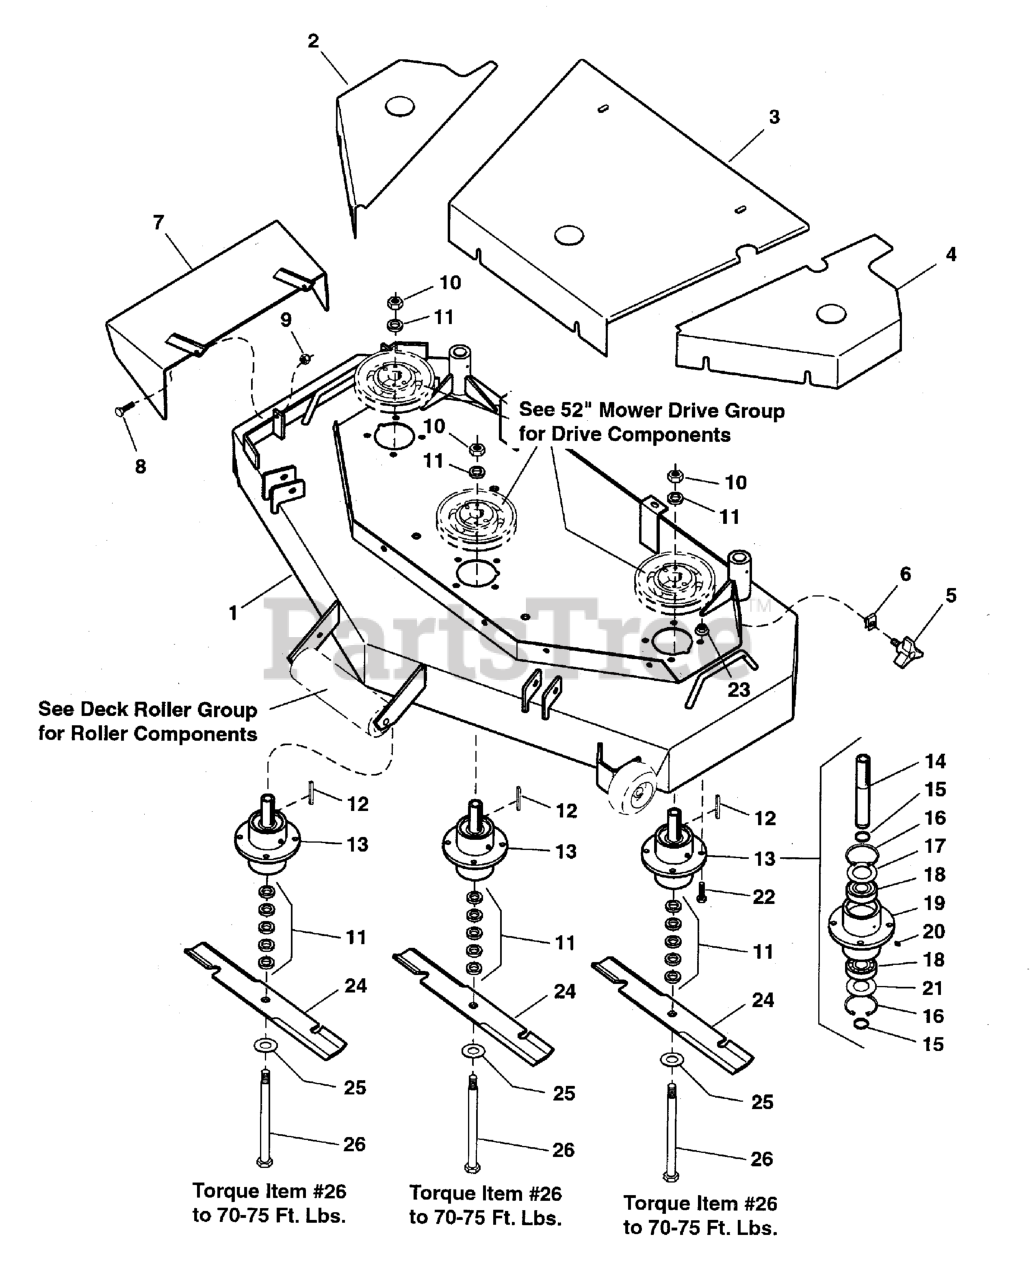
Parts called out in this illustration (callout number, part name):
1	DECK SHELL W/DECALS, 52 DDSH52
2	SPINDLE COVER, RH
3	SPINDLE COVER, Center
4	SPINDLE COVER, LH
5	KNOB
6	BODY CLIP, 5/16-18-7GA MATERIAL
7	CHUTE, DISCHARGE WELDMENT
8	BOLT, 5/16-18 X 1 GD5 YZ
9	NUT, 5/16-18 Hex Nylon Lock
10	NUT, 5/8-11 Hex
11	SPACER, .63 x 1.06 x .23
12	KEY, 1/4 SQ. X 2-1/2
13	SPINDLE ASSEMBLY, Complete
14	SPINDLE SHAFT
15	SNAP RING, External
16	SNAP RING, Internal
17	SPINDLE WASHER, Top
18	BEARING
19	SPINDLE HOUSING
20	GREASE FITTING
21	SPINDLE WASHER, Bottom
22	BOLT, 5/16-18 x 1-1/4
23	NUT, 5/16-18 HEX SERRATED FLANGE (LARGE)
24	MOWER BLADE, 18"
25	WASHER, 5/8" USS
26	BOLT, 5/8-11 x 9-1/2
